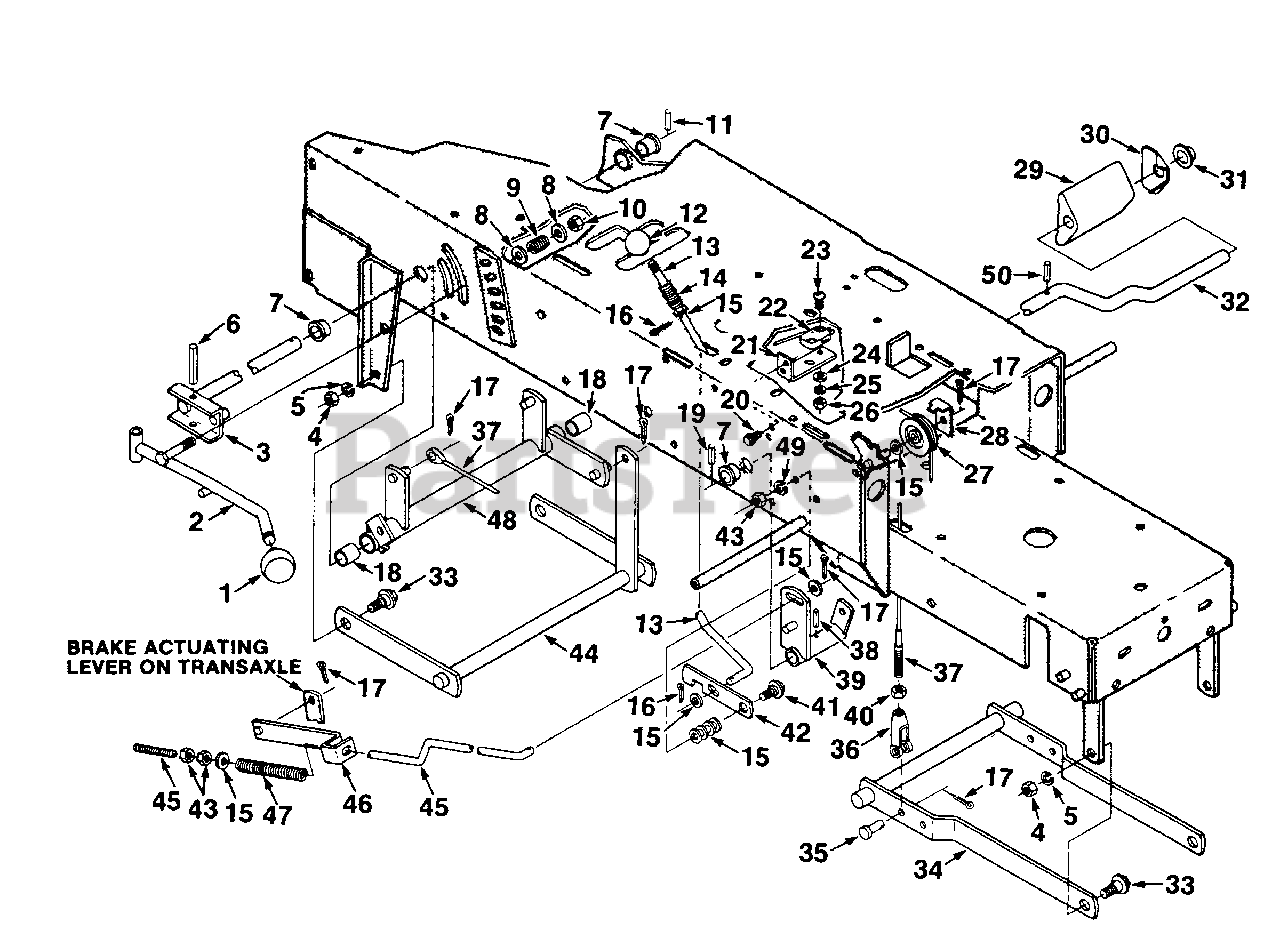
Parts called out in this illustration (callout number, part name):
1	KNOB- Implement lift handle
2	HANDLE- Lift
3	LIFT HANDLE BRACKET & ROD ASSY.
4	NUT- 3/8-16 hex
5	WASHER- Lock 3/8 hvy.
6	PIN- Groove 5/16 x 2 1/4
7	BEARING- Flanged
8	WASHER- Flat 3/8
9	SPRING- Compression
10	NUT- 5/16-18 hex centerlock
11	PIN- 3/16 x 1
12	KNOB- Parking brake
13	ROD- Crake lock
14	SPRING- Compression
15	WASHER- Flat 11/13
16	PIN- Cotter 1/8 x 3/4
17	PIN- Cotter 3/32 x 3/4
18	BUSHING- Pivot
19	PIN- Roll 1/8 x 1 1/4
20	BOLT- 1/4-14
21	BRACKET- Safety switch
22	SWITCH- Safety
23	SCREW #4-40 x 1.00 slotted truss hd.
24	WASHER- Flat 1/8 - 5/16 x 1/32
25	WASHER- Lock #4 Reg
26	NUT- #4-40 hex
27	PULLEY- Lift cable
28	RETAINER- Lift cable
29	PEDAL- Clutch
30	PEDAL- Safety stop Clutch
31	NUT- 5/8 push on
32	ROD- Clutch
33	BOLT- Shoulder
34	DRAG LINK ASSY.
35	PIN- Clevis
37	CABLE- Deck lift
38	PIN- 5/32 x 1 grooved
39	CLUTCH ROD ACTUATOR ASSY.
40	NUT- 5/16-24 hex jam
41	BOLT- Idler pivot
42	LATCH- Parking brake
43	NUT- 5/16-18 hex
44	REAR LIFT BAR ASSY.
45	ROD- Brake
46	BRAKE SPRING BRACKET ASSY.
47	SPRING- Brake compression
48	REAR LIFT & BUSHING ASSY.
49	WASHER- Lock 5/16 hvy.
50	PIN- Roll
